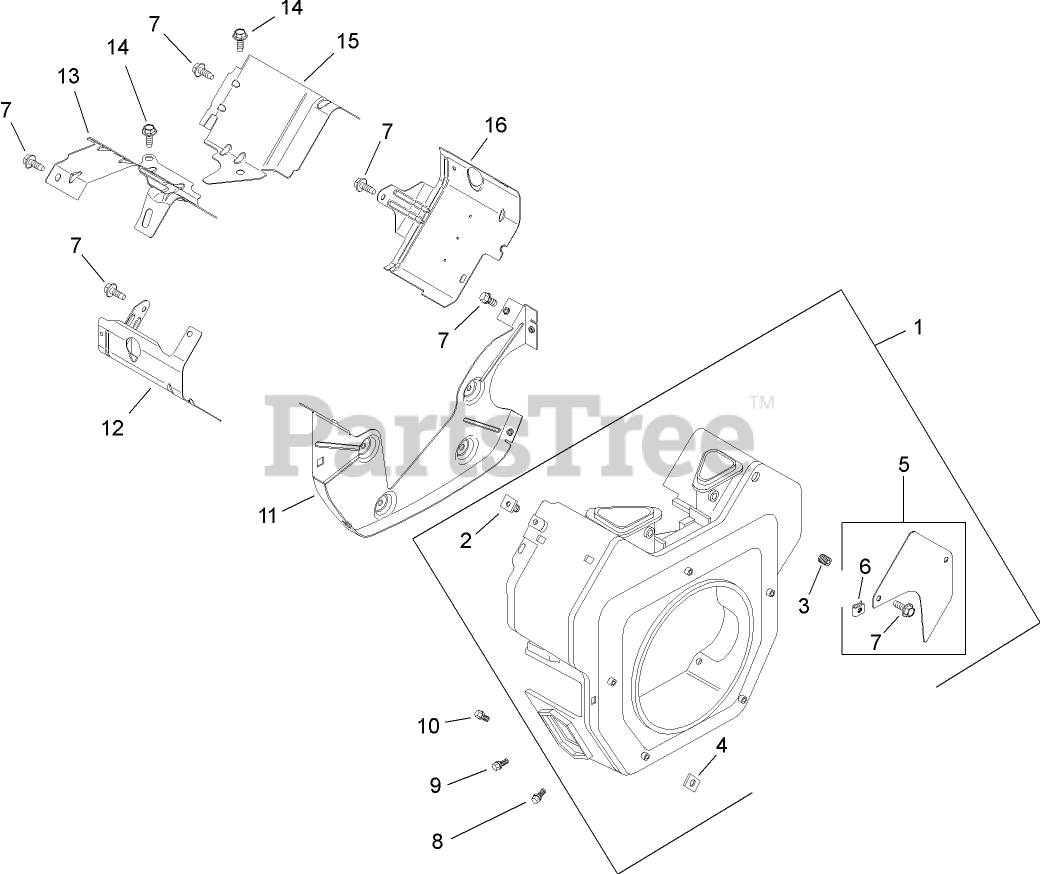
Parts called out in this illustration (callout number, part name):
1	Housing-Blower
2	NUT-PLASTIC
3	Screw-Set (10-24X.25)
4	Nut-Plastic
5	Access Panel Kit
6	Clip-Mounting
7	SCREW-FLANGE, THREAD FORMING (M6X1.0X16)
8	SCREW-FLANGE, THREAD FORMING (M5X.80X16)
9	SCREW-FLANGE, THREAD FORMING (M5X0.8X16)
10	SCREW-FLANGE, THREAD FORMING (M5X.8X20)
11	Plate-Backing
12	Baffle-Barrel, Cylinder (No. 2 Side)
13	BAFFLE-VALLEY (No. 2 SIDE)
14	SCREW-HHFTF (M5X.80X10)
15	BAFFLE-VALLEY (No. 1 SIDE)
16	Baffle-Barrel, Cylinder (No. 1 Side)
